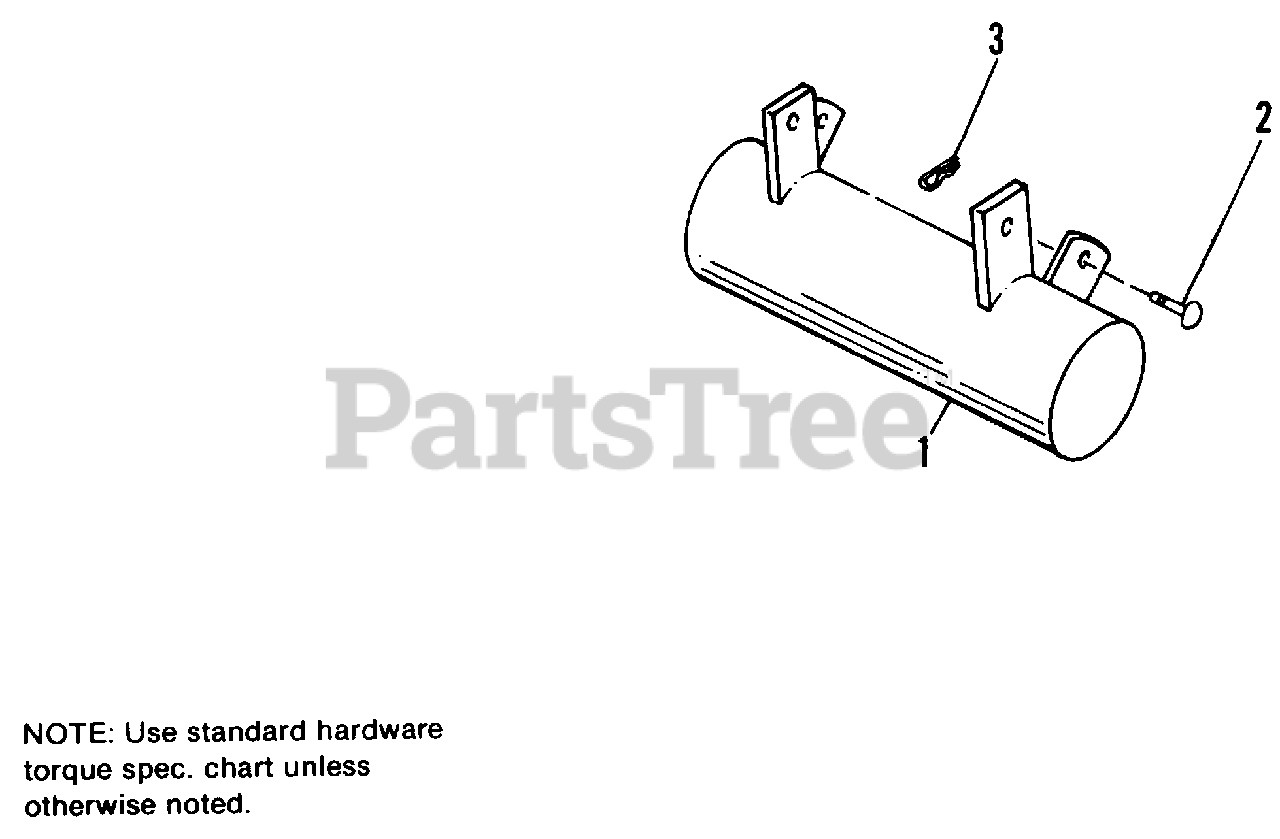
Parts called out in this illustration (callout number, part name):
1	WEIGHT ASSY.
2	PIN
3	PIN, Quick, 1-7/8
